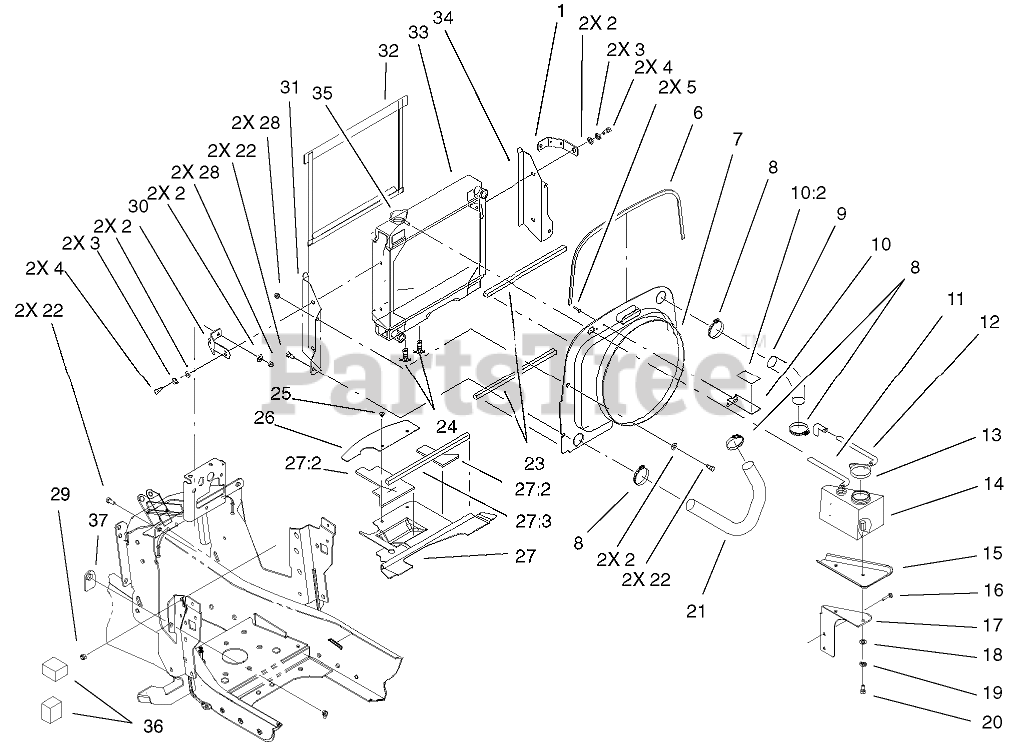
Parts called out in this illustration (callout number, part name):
1	Strap-Radiator
2	Washer-Flat (only on: 73590)
3	WASHER-LOCK
4	SCREW-HH
5	RIVET-POP
6	Trim-Loc
6	TRIM - LOC 31"
7	SHROUD - FAN
8	CLAMP-HOSE
9	HOSE - RAD. DAIHATSU
10	FAN/DECAL ASM
10:2	DECAL - WARNING
11	HOSE - FUEL LINE
12	HOSE - OVERFLOW
13	CAP - COOLANT RESERVOIR
14	BOTTLE - OVERFLOW
15	TRAY - OVERFLOW
16	BOLT-CARR
17	Brkt-Bottle
18	WASHER-FLAT
19	WASHER-LOCK
20	SCREW-HH
21	HOSE - RAD. DAIHATSU
22	SCREW-HH
23	FOAM - RADIATOR/SHROUD
24	VALVE - DRAIN
25	RIVET - PLASTIC
26	BAFFLE - TOWER REAR
27	BAFFLE-TOWER ASM
27:2	FOAM - BAFFLE
27:3	FOAM - RADIATOR/SHROUD
28	NUT-LOCK, NI
29	NUT-HEX
30	Bracket-Relay
31	Support-Radiator RH
32	SCREEN - CHAFF
33	RADIATOR - DIESEL
34	Support-LH Radiator
35	CAP-RADIATOR
36	SEAL-FOAM, SIDE
37	WASHER - SPACER
